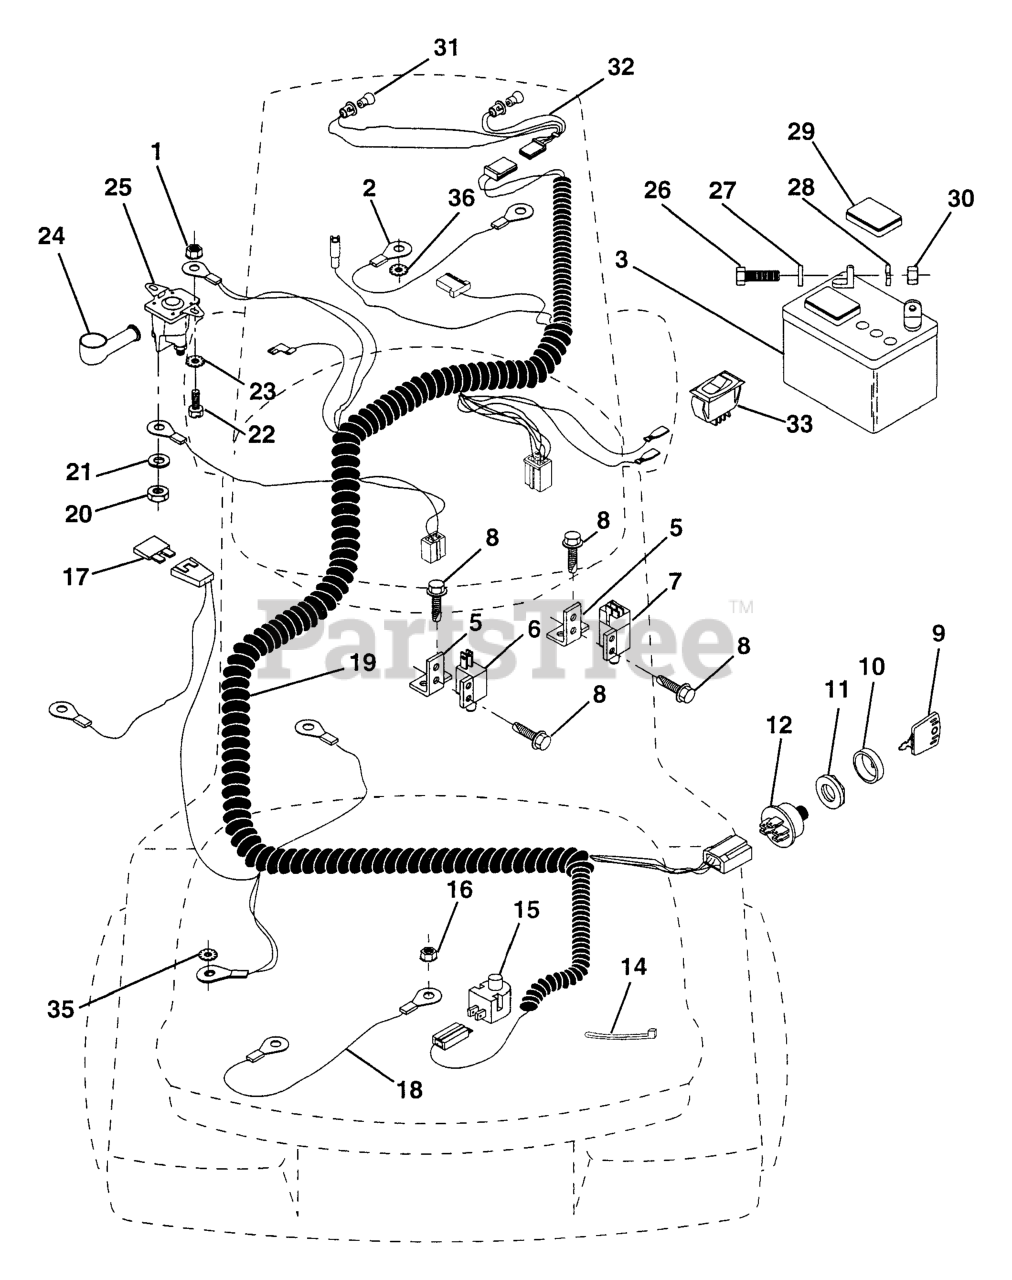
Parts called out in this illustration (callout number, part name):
1	NUT
2	CABLE.BATTERY.6GA.16"RED
3	BATTERY
5	BRACKET LT
6	SWITCH-INTER. GT
7	SWITCH INTERLOCKT
9	KEY, SET OF 2
10	COVER KEY IGNITIO
11	NUT IGNITION
12	SWITCH
14	TIE GUIDE
15	RP.SWITCH.PLUNGER.NC.GRAY
16	NUT
18	CABLE ASSY
19	IGNITION HARNESS
20	NUT
21	LOCKWASHER
22	BOLT
23	Washer, Lock Ext. Tooth 1/4
24	TERMINAL COVER
25	SOLENOID
26	BOLT.HEX.1/4.X.3/4.DICHROMATE
27	WASHER
28	LOCKWASHER
29	CAP BATTERY NLA
30	NUT
31	BULB-LIGHT T
32	HARNESS, LIGHT SOCKET
35	LOCKWASHER
36	Washer Lock Inter. Tooth 1/4
